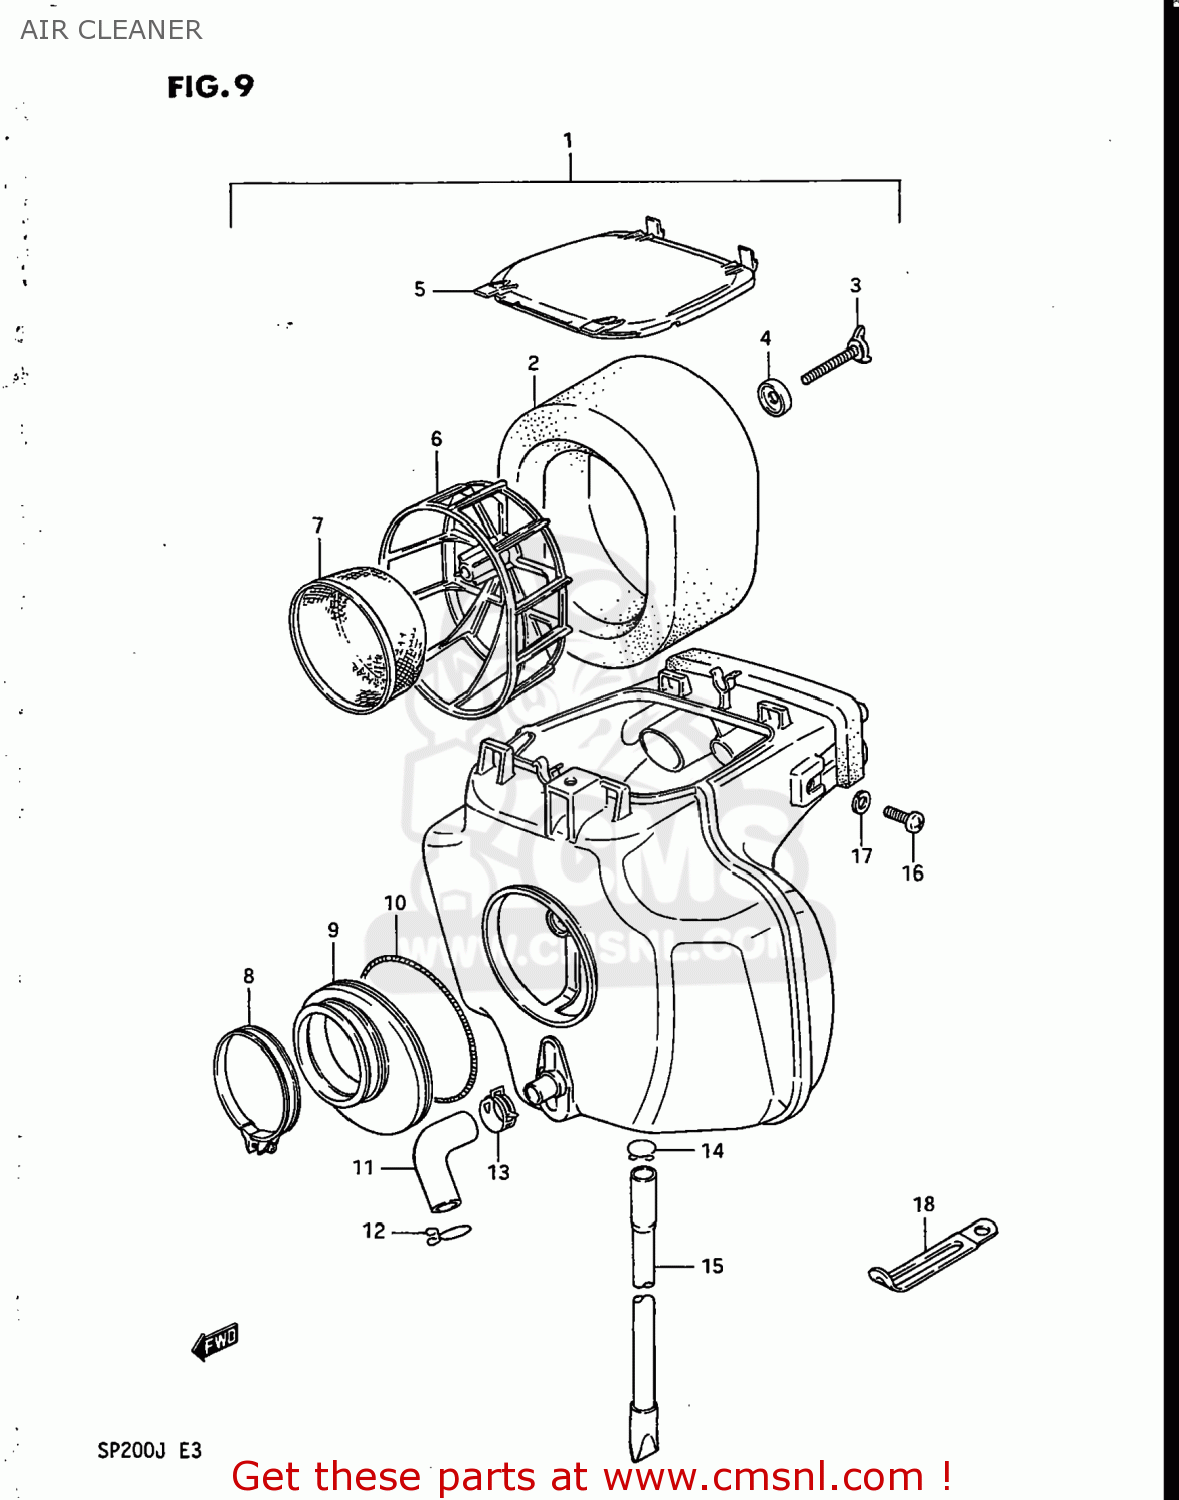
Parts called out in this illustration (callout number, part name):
1	CLEANER ASSEMBLY,AIR
2	FILTER,AIR CLEANER
3	BOLT,WING
4	WASHER,FILTER HOLDER
5	CAP
6	HOLDER,FILTER
7	TRAP
8	CLAMP
9	TUBE,AIR CLEANER OUTLET
10	CLAMP,AIR CLEANER SIDE
11	TUBE,BREATHER
12	CLIP,BREATHER TUBE
13	CLIP
14	CLIP
15	DRAIN TUBE
16	SCREW
17	WASHER,LOCK
18	CLAMP
